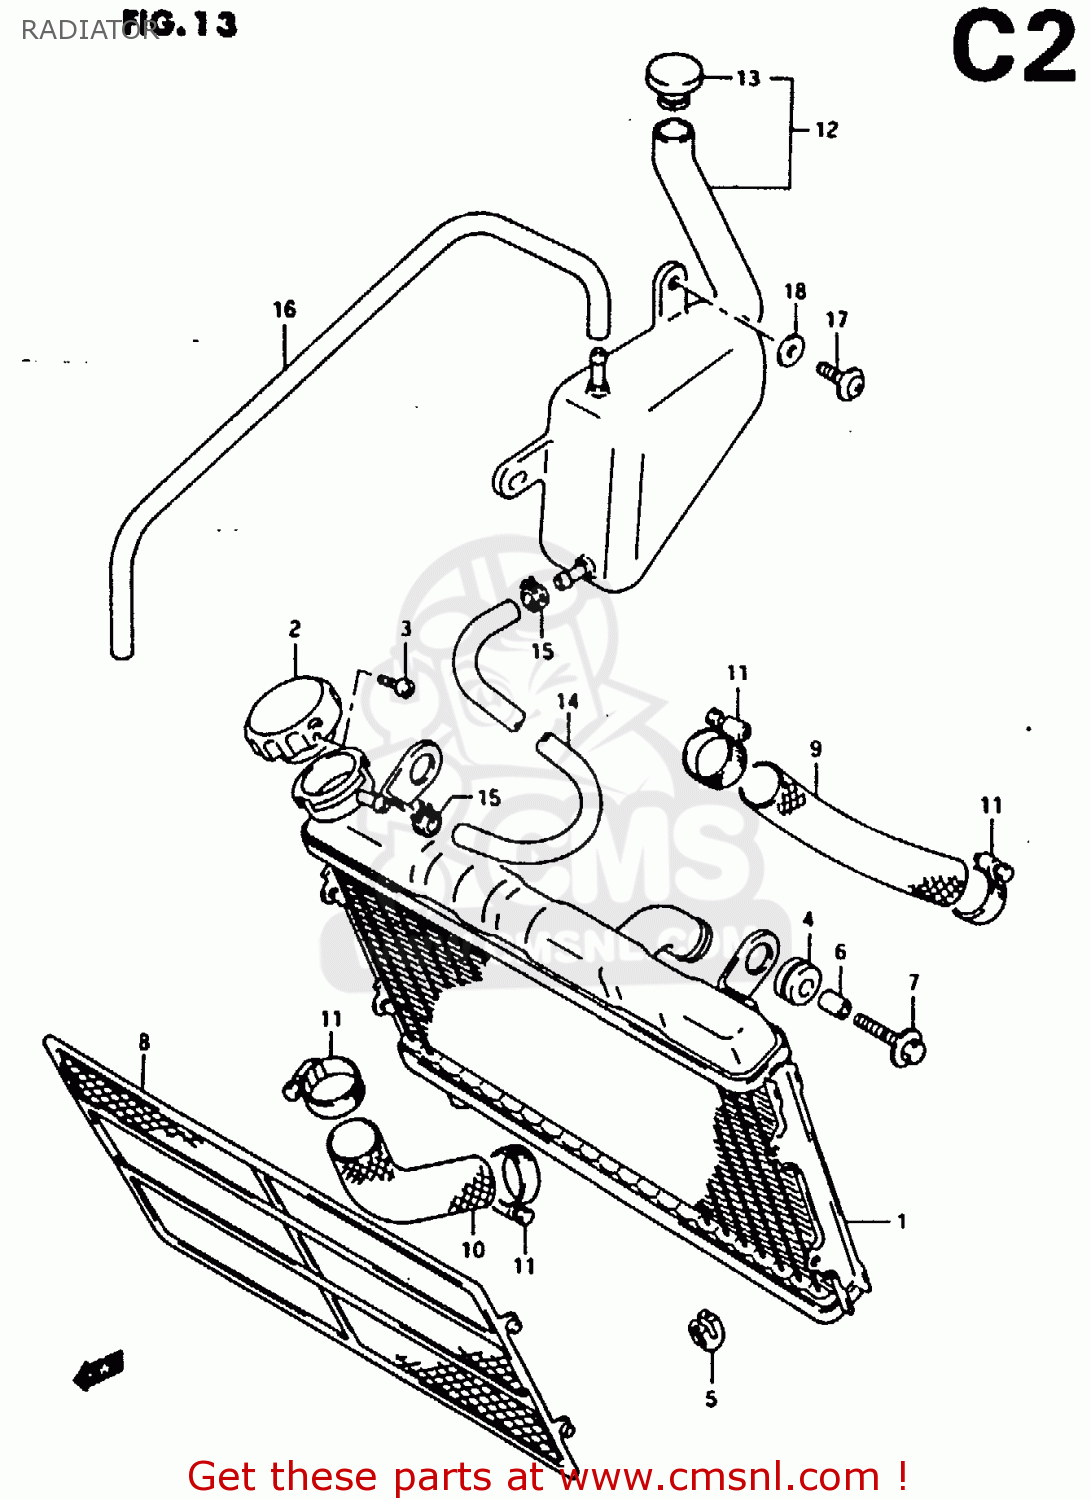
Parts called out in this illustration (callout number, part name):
1	RADIATOR, WATER
2	CAP COMP,RADIATOR 1.1
3	SCREW,RADIATOR CAP
4	CUSHION
5	CUSHION,OIL COOLER NO.2
6	SPACER (6.8X10X12)
7	BOLT(6X25)
8	NET,RADIATOR
9	HOSE, RADIATOR, INLET
10	HOSE,RADIATOR OUTLET
11	CLAMP
12	TANK,RESERVOIR
13	CAP,RESERVOIR TANK
14	HOSE(5X9X2000)
15	CLIP
16	HOSE
17	SCREW(6X20)
18	WASHER
